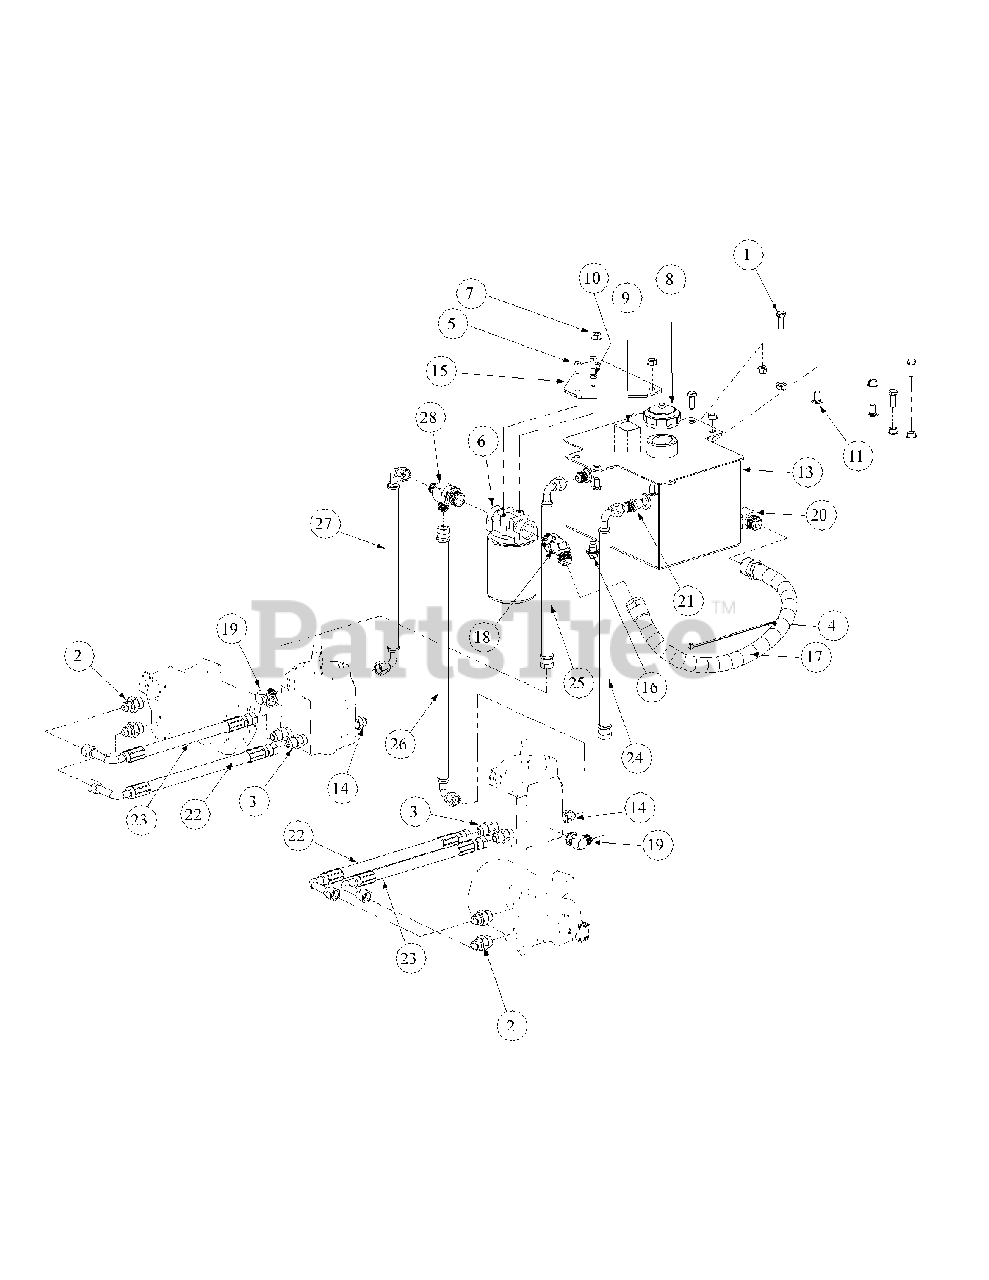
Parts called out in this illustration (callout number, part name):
1	Hex Cap Screw, 3/8-16, 1
2	Fitting 1/2 x 3/4 - O Ring
3	Fitting 1/2 x 3/4 - O Ring to Flare
4	Cable Tie, 3/16 x .05 x 7.4
5	Hex Cap Screw, 1/4-20, .75
6	Filter Head 3/4
7	Hex Nut Flange Lock, 3/8-16
8	Cap, Hydro Oil Tank
9	Decal Oil Only 20W50
10	Lock Washer, 1/4
11	Carriage Bolt, 3/8-16 x .75 LG.
13	Hydraulic Tank Assembly
14	Fitting Connector, 1/2 x 3/8
15	Oil Filter Mounting Plate
16	Oil Pan Drain w/ Seal and Plug
17	Tank to Filter Hose Assembly
18	Connector, 3/4 x3/4
19	Elbow Fitting, 3/8 O-ring, 1/2 Flare
20	Fitting Elbow, 1/2 x 1/2
21	Fitting, 3/8 NPT, 1/2 Flare
22	Long Pressure Hose Assembly
23	Short Pressure Hose Assembly
24	17.75" Return Hose Assembly, RH
25	14" Return Hose Assembly, LH
26	21.25" Supply Hose Assembly, RH
27	15.50" Supply Hose Assembly, LH
28	Tee Fitting, 3/4 x 1/2 x 1/2
